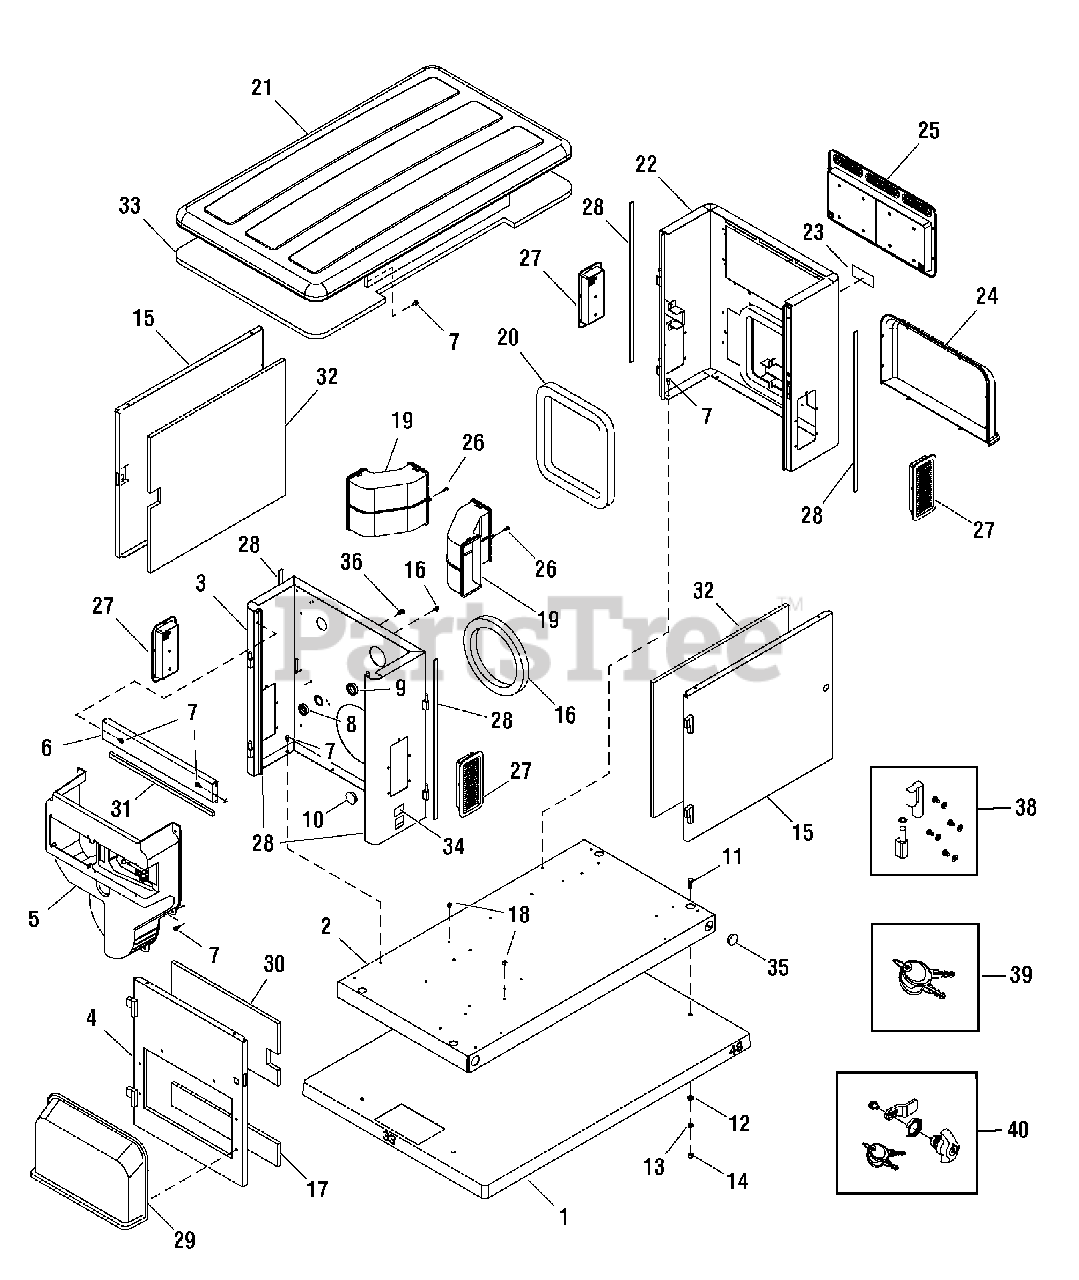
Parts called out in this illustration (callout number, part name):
2	BASE, Mounting
3	BULKHEAD ASSEMBLY, Engine
4	DOOR ASSEMBLY, Engine
6	SUPPORT RAIL ASSEMBLY
7	BOLT
9	BUSHING, Snap, 1-1/2
11	* CAPSCREW, Hex Head, 3/8-16 x 1
12	* WASHER, Flat, 3/8-M10
13	* WASHER, Lock, 3/8
14	* NUT, 3/8-16
16	SEAL, Foam
17	INSULATION, Engine Door, Bottom
18	MOUNT, Tie Wrap
22	BULKHEAD, Alternator
24	COVER, Air Intake
25	ASSEMBLY, Vent, Exhaust
29	COVER, Air Intake, Engine
30	INSULATION, Engine Door, Top
34	DECAL
